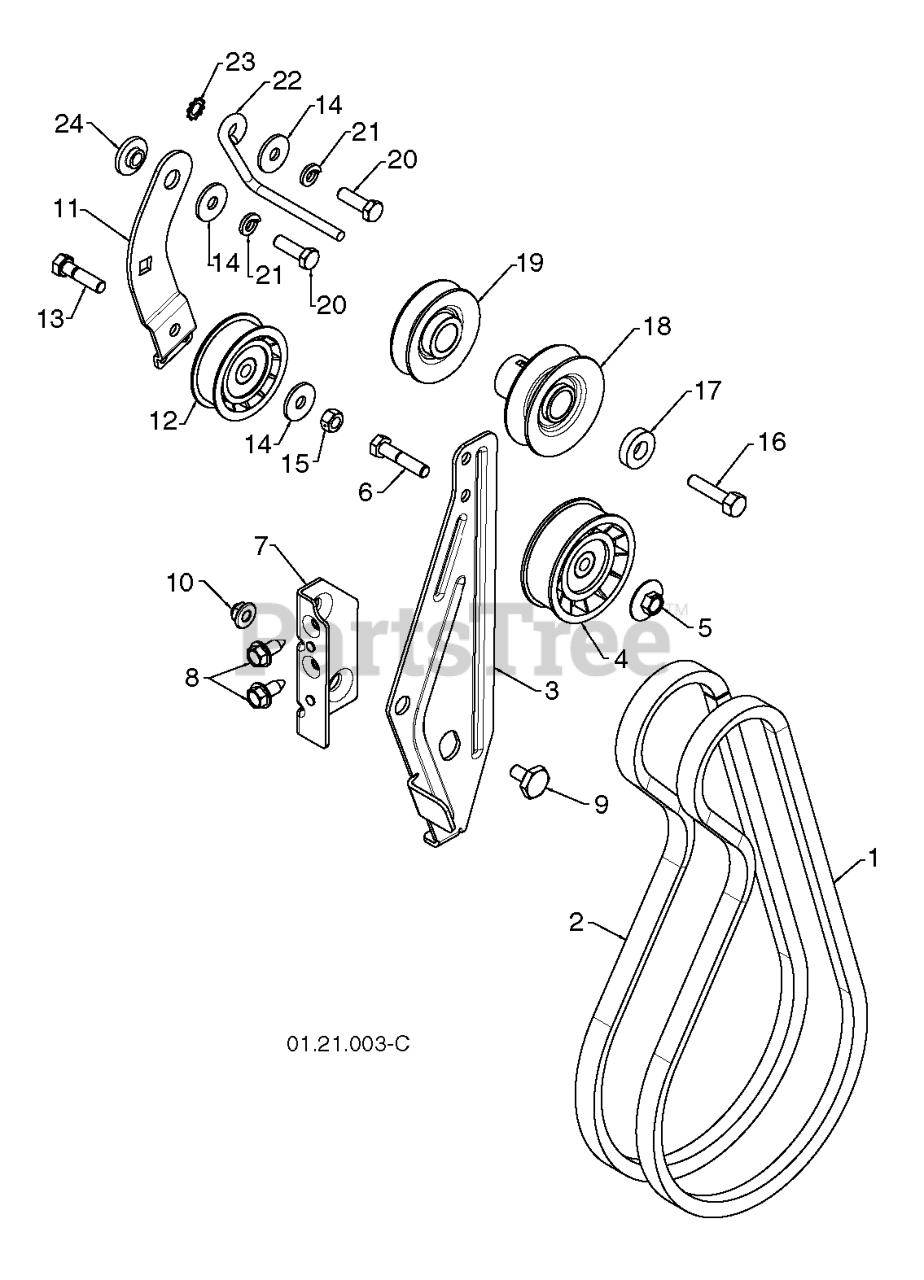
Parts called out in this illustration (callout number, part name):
1	TUBE HANDLE
1	BELT.V.IMPELLER
2	V-BELT TRACTION 34.25
3	NUT T
3	ARM.IDLER.BRAKE
4	HANDLE.BAGGER.W/LVRS.BLK.CRD
4	PULLEY.W/SPACER.2.75
5	SCREW.PAN.HEAD
5	NUT.FLANGE.HEX.5/16X18.BLACK
6	REPL BY 532 75 00-29
6	HEX BOLT
7	RP BRACKET.IDLER
8	COVER.PNT.BGR.CRD.WSLOTS.MS668
8	BOLT.HEX.HD.WASHER.5/16-18X.75
9	Bolt Carriage 1/4-20 x 2.25d x Gr.5
9	BOLT.SHOULDER.1/2X12
10	TUBE
10	NUT.LOCK.5/16-18
11	BRACKET.SUPPORT.UPPER.BAG.CRD
11	ARM, IDLER
12	BRKT PIVOT
12	PULLEY.W/SPACER.2.25
13	BOLT.5/16-18X1-1/4 FULL.THREAD
14	BOLT-HEX EAK
14	STEEL WASHER
15	RETAINER-SPRNG RB
15	NUT.71038.31-18.HEX.NYLOCK
16	NUT LOCK FLG 3/8-16 UNC
16	SCREW, HEX HD 3/8-24 X 1-3/8
17	RP BOLT 5/16-18 X3/4 ZN/YEL GR
17	WASHER, FLAT 3/8
18	PULLEY.IMPELER.
19	NUT LOCK HEX FLANGE 5/16-18
19	PULLEY.ENG.TRACTION
20	BRKT.PIVOT.RH.CRD
21	BAGGER.ASM.CRD.2007
21	WASHER.LOCK.HVY.HLCL.SPR.5/16
22	BRKT.SIDE.BAG.CRD
22	BELT.GUIDE.RH
23	WASHER EXT TOOTH LOCK 5/16
24	TUBE.PIVOT.BAG.CRD.BLACK
24	RP BUSHING, IDLER PIVOT
25	PIPE
28	GRIP.HANDLE.BLACK
31	RETAINER CLIP
32	RIVET,DRILLED
33	MULCH PLUG, CTH150
34	HANDLE.MULCHER.92.CRD (2 2)
36	WASHER
37	Plug Support Bagger CRD
38	BOLT.5/16-18X2.5
39	SEAL.BAGGER.CRD
41	BRKT.VERT.ADJ.BAGGER.CRD
43	PLUG, TUBING END
46	BOLT.CARRIAGE.5/16-18
47	PIPE
49	ROD
50	NUT.71038.31-18.HEX.NYLOCK
51	LATCH
53	NUT
54	BOLT
